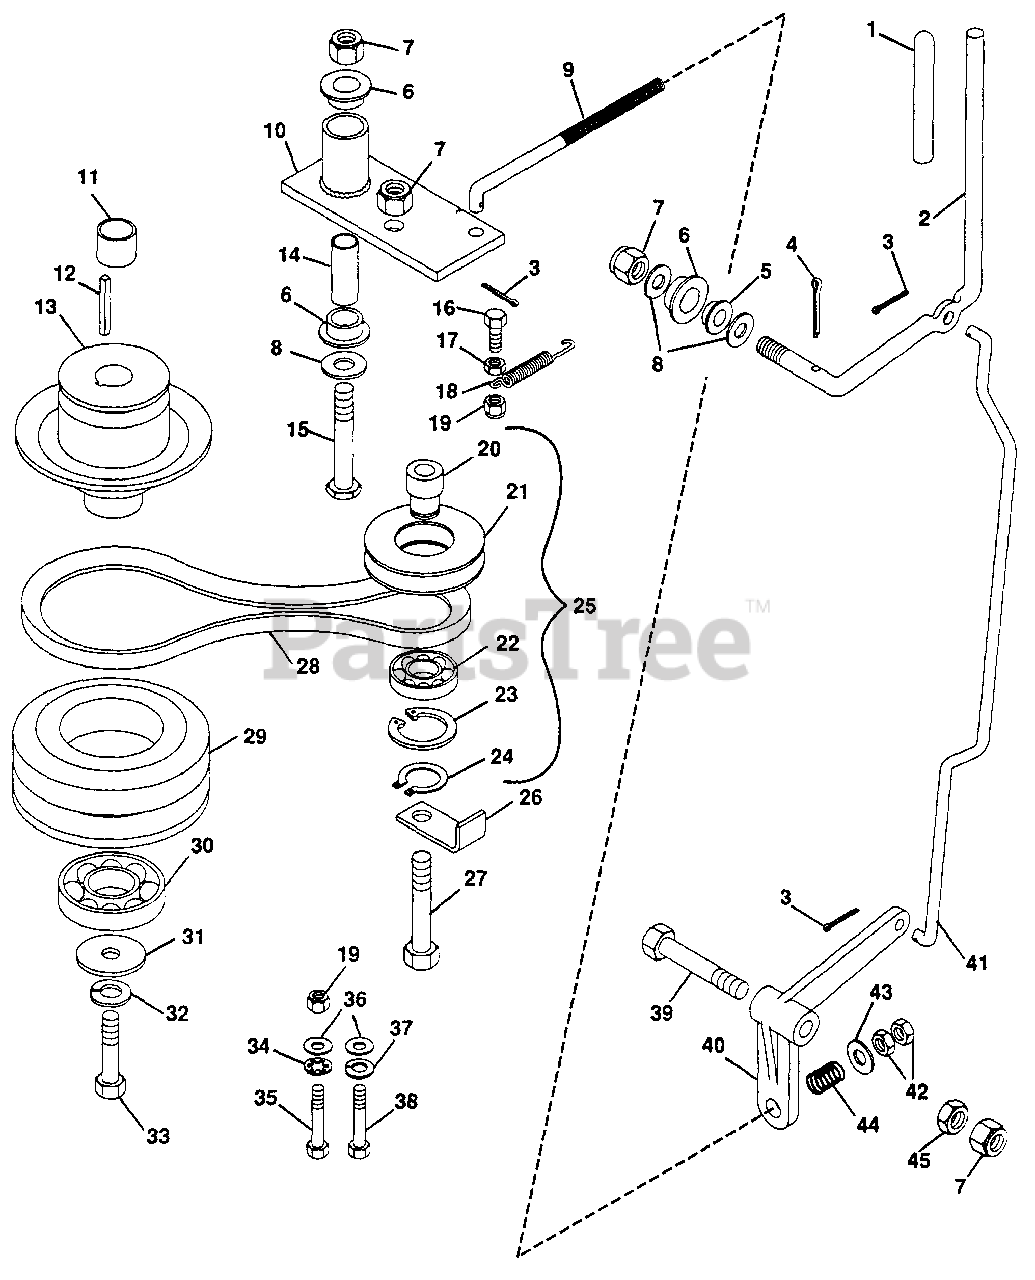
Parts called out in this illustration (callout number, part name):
1	GRIP, PTO LEVER
2	LEVER, PTO ACTUATING
3	PIN, COTTER .09X.75
4	PIN, COTTER .187X1.50
5	BUSHING, FLANGE NYLON
6	BUSHING, FLANGE NYLON
7	NUT, LOCK 1/2-13
8	WASHER, FLAT .531X1.250X.100
9	ROD, PTO CLUTCH ACTUATING
10	WELDMENT, PTO IDLER
11	SPACER, MANUAL START
12	KEY, SQUARE .250X2.375
13	WELDMENT, PTO CLUTCH HUB
14	BUSHING, ST. .560X.745X2.04 STL.
15	BOLT, HEX 1/2-13X2.75 SPECIAL
16	BOLT, HEX 5/16-18X1.00
17	NUT, HEX 5/16-18
18	SPRING, PTO RETURN
19	NUT, LOCK 5/16-18
20	BUSHING, FLANGE STEEL
21	SHEAVE, IDLER
22	BEARING, BALL
23	RING, RETAINING
24	RING, RETAINING
25	ASSEMBLY, IDLER SHEAVE
26	GUIDE, BELT
27	BOLT, HEX 1/2-13X2.50
28	V-BELT, PRO PTO
29	SHEAVE, MOWER CLUTCH
30	BEARING, BALL 1.574X3.149X.708
31	WASHER, SPECIAL
32	WASHER, LOCK 7/16 REG.
33	BOLT, HEX 7/16-20X2.50
34	WASHER, LOCK 5/16 INT. TOOTH
35	BOLT HEX 5/16-18X1.75
36	WASHER, FLAT .344X.688X.065
39	BOLT, HEX 1/2-13X2.75
40	LEVER, PTO CLUTCH
41	ROD, PTO CONTROL
42	NUT, HEX 3/8-16
43	WASHER, FLAT .406X.812X.065
44	SPRING, COMP. 1X.78X338
45	NUT, HEX 1/2-13
